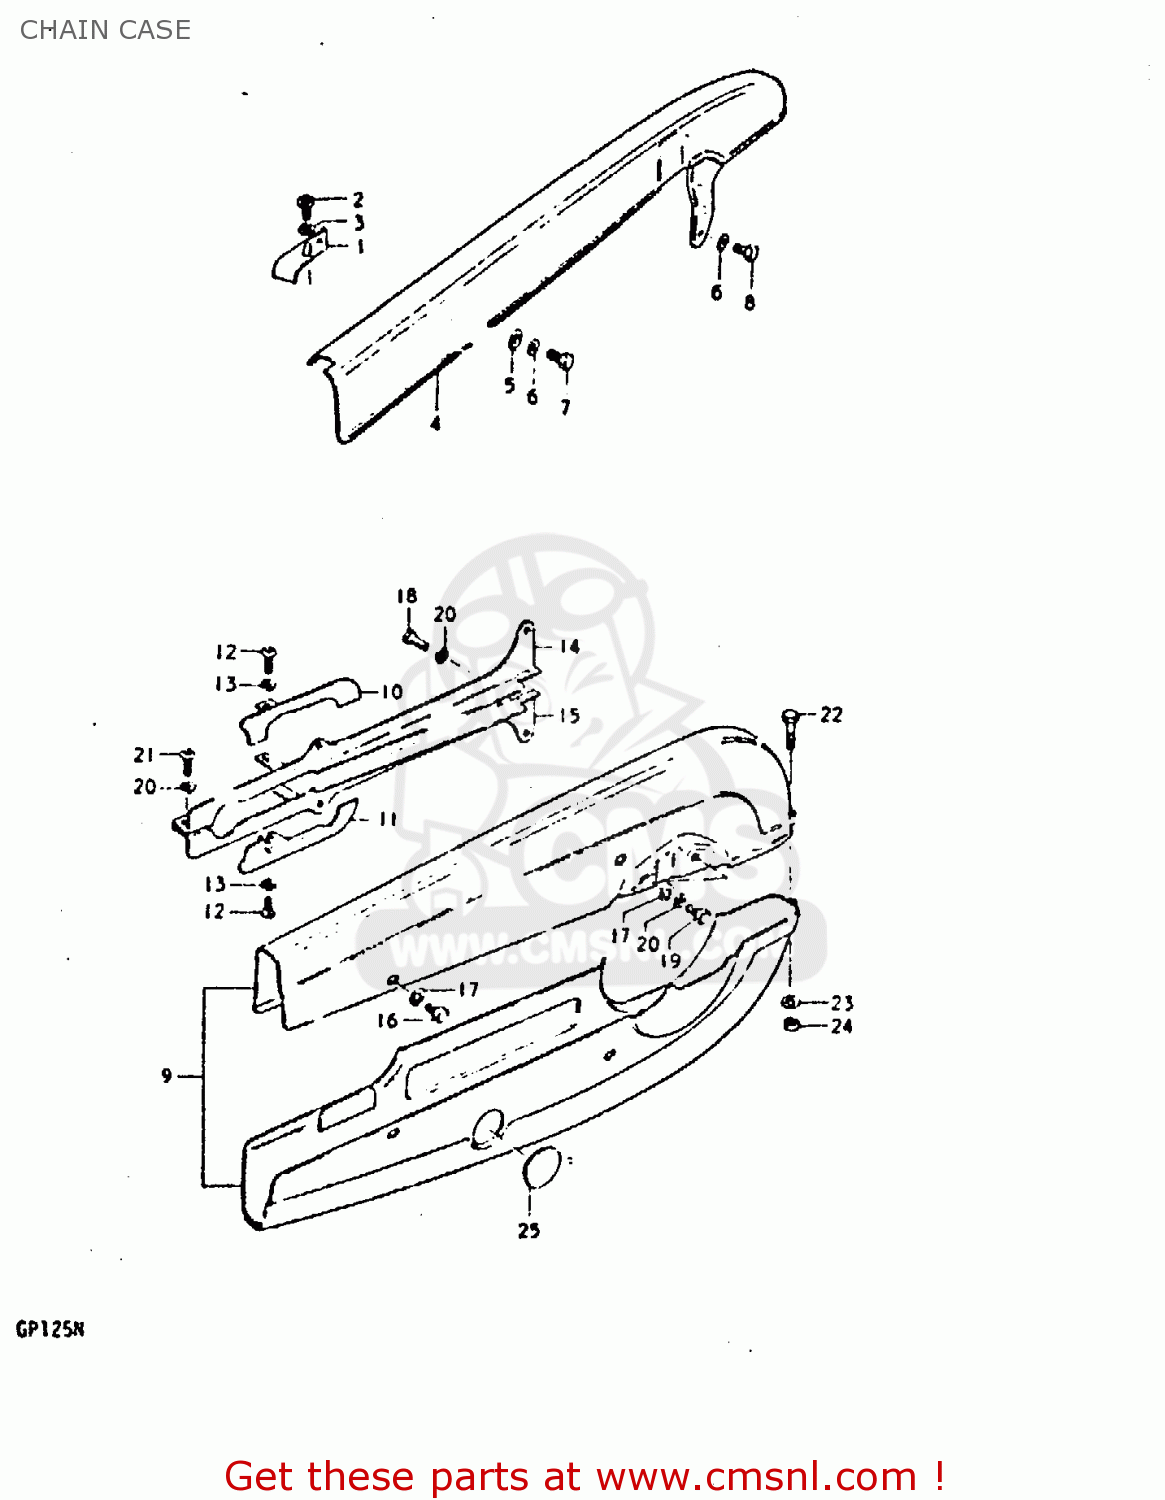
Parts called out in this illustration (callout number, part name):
1	BRACKET, CHAIN CASE FRONT
2	SCREW
3	LOCK WASHER
4	CHAIN CASE
5	WASHER
6	LOCK WASHER
7	BOLT
8	BOLT
